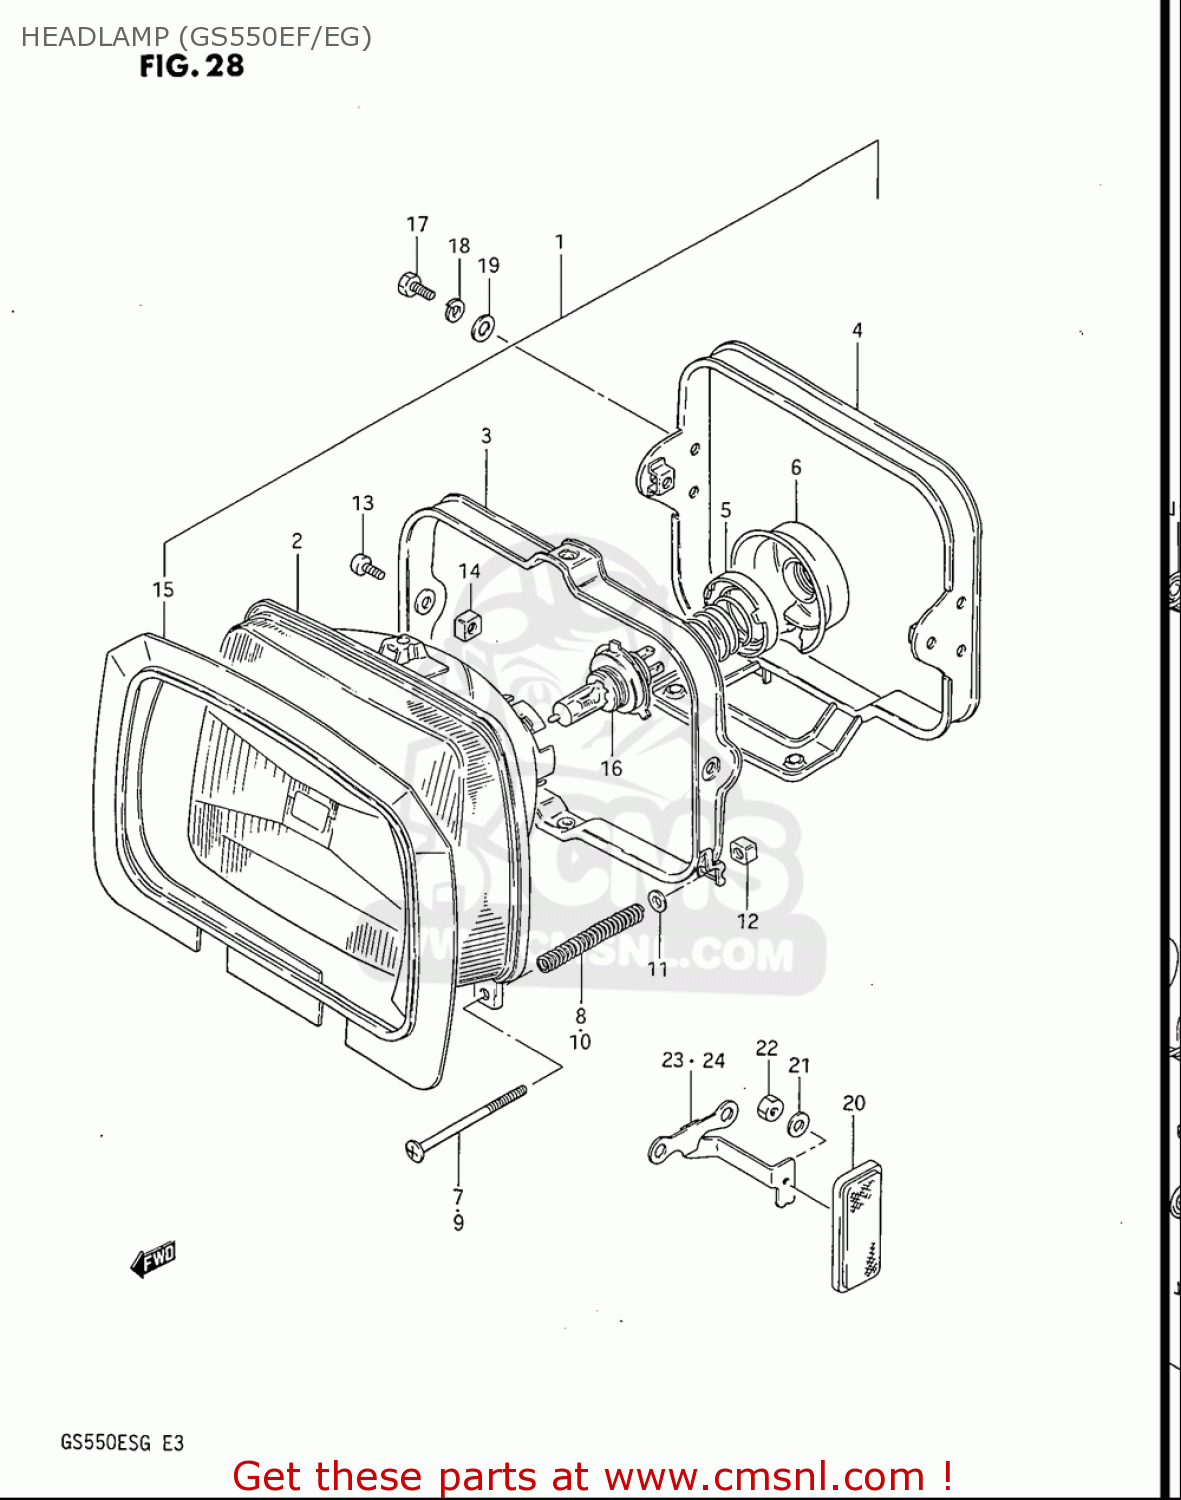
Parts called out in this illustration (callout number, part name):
5	HOLDER
6	COVER,SOCKET
7	SCREW(4X50)
8	SPRING
9	SCREW
10	SPRING,HEADLAMP ADJUST
11	WASHER
12	NUT
13	SCREW
14	NUT
15	SHADE
16	BULB(12V60/55W,H4)
17	BOLT
18	WASHER,LOCK
19	WASHER
20	REFLEX REFLECTOR,FR SIDE
21	WASHER
22	NUT
